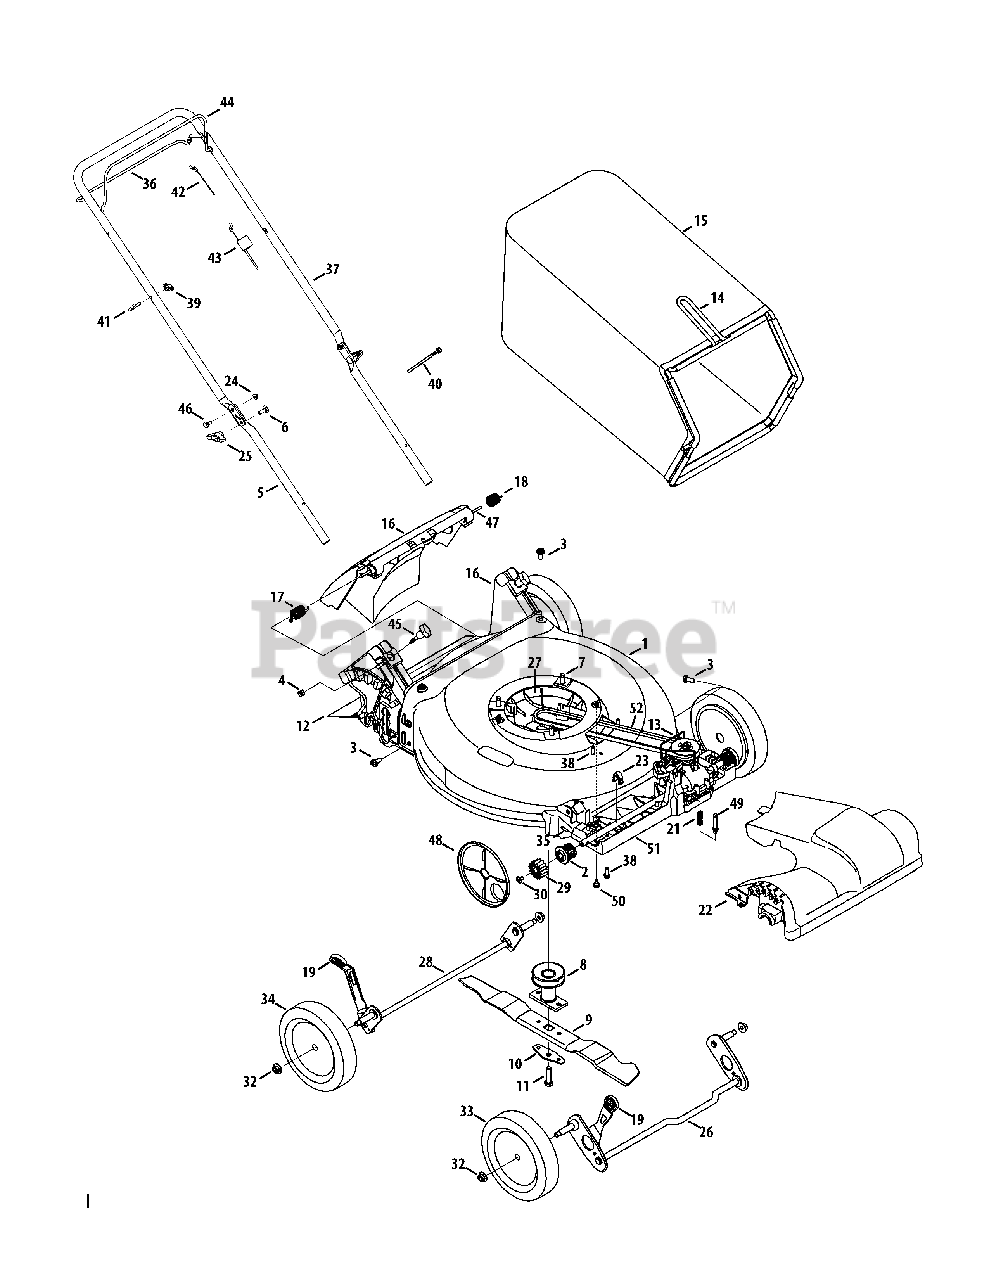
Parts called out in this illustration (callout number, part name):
1	Deck , 21"
2	Bearing Assembly
3	Screw, 5/16-14 x .750
4	Nut, Sq., 1/4-20
5	Lower Handle
6	Carriage Screw ,5/16-18
7	Screw, 3/8-16 x 1.00
8	Blade Adapter
9	Mulching Blade
10	Blade Bell Support
11	Screw, 3/8-24 x 1.50
12	Trailing Shield
13	Transmission Wire
14	Grass Catcher Frame
15	Grass Bag
16	Rear Discharge Door Assembly
16	Rear Door Assembly (Briggs)
17	Torsion Spring - RH
18	Torsion Spring - LH
19	Adjustment Lever Knob
20	Screw, 1/4-20 x .500
21	Compression Spring
23	Front Axle Clip
24	Nut, Flange Lock, 1/4-20
25	Wing Knob
26	Front Axle Assembly
27	Engine Baffle
28	Rear Axle Assembly
29	Spur Gear, 14T - RH
29	Spur Gear, 14T - LH
30	Screw, 1/4-20 x .390
31	Transmission Assembly
32	Flange Lock Nut, 3/8-16
33	Front Wheel
34	Rear Wheel
35	Dowel Pin
36	Drive Control
37	Upper Handle
38	Screw, 1/4-15 x .750
40	Cable Tie
41	Rope Guide
42	Control Cable
42	Control Cable (Briggs)
43	Drive Cable
44	Blade Control
45	Wing Nut
46	Sldr. Screw, .375 x .126 x 1/4-20
47	Pivot Rod
48	Wheel Dust Cover
49	Spring Body
50	Scr., Shldr., 1/4-20 x .50
51	Lower Tray
